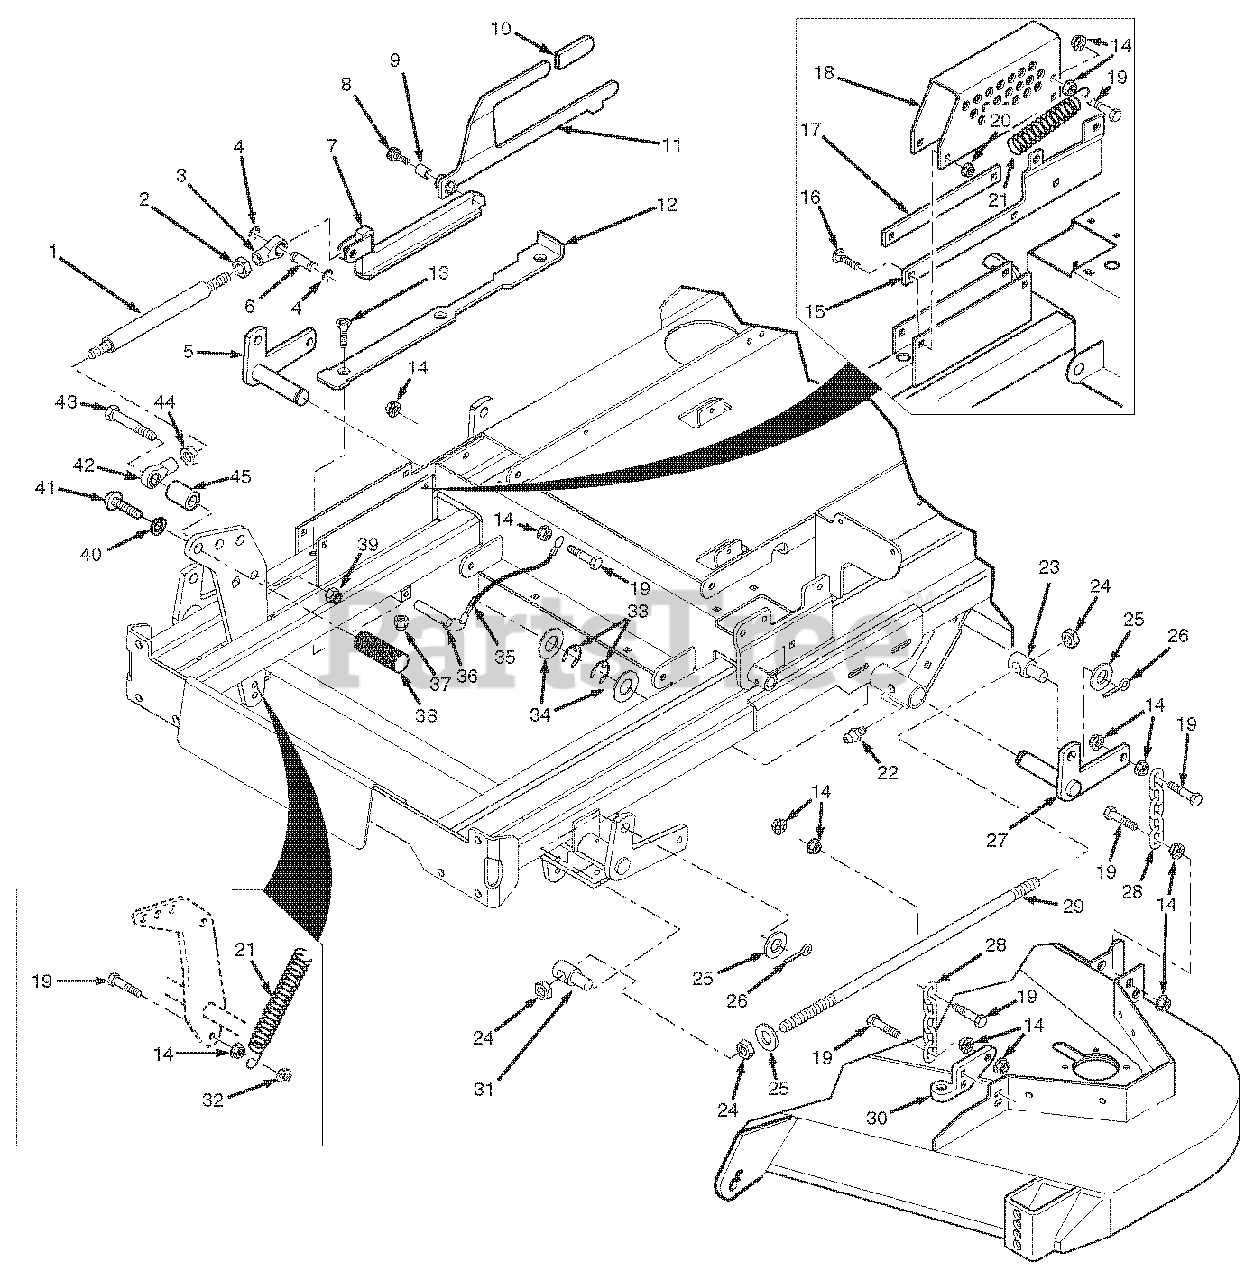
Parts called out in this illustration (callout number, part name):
1	Link, Deck Lift
2	Nut, Jam 1/2-20 LH
3	Rod End, Female - 1/2-20 LH
4	Ring, Retaining 1/2" External "E"
5	Bellcrank Weldment, RH Rear
6	Pin, Decklift
7	Slide Weldment, Height Adjustment
8	Bolt, Shoulder 1/2 x 3/4"
9	Bushing, .502 ID.
10	Grip, Deck Latch
11	Deck Latch
12	Lockplate, Decklift
13	Screw, Cap 5/16-18 x 3" FHHS
14	Nut, Hex Serrated Flange 3/8-16
15	Guide, Long
16	Bolt, Carriage 5/16-18 x 1"
17	Guide, Short
18	Bracket, Cutting Height Adjustment
19	Bolt, Hex Head 3/8-16 x 1-1/2"
20	Nut, Hex Serrated Flange 5/16-18
21	Spring, Helper
22	Grease Fitting
23	Swivel Joint, LH
24	Nut, Hex 5/8-11
25	Flatwasher, 5/8" (.656 x 1.312 x .095)
26	Cotter Pin, 3/16 x 1"
27	Bellcrank Weldment, LH Rear
28	Chain
29	Stud, 5/8-11 x 26.0"
30	Lever Assembly, Deck Level
31	Swivel Joint, RH
32	Locknut, 3/8-16 Center Lock
33	Ring, Retaining 1" External "E"
34	Flatwasher, 1" (1.062 x 1.50 x .048)
35	Lanyard, Deck Height Pin
36	Ring Pin, 1/2 x 3.06"
37	Nut, 3/8-16 Elastic Stop
38	Foot Pedal, Height Adjustment
39	Nut, Hex Elastic Stop 1/2-13
40	Lockwasher, 5/8"
41	Capscrew, 5/8-11 x 1-1/2"
42	Rod End, Female - 1/2-20 RH
43	Bolt, Hex Head 1/2-13 x 3"
44	Nut, Jam 1/2-20 RH
45	Spacer, Decklift Pedal
